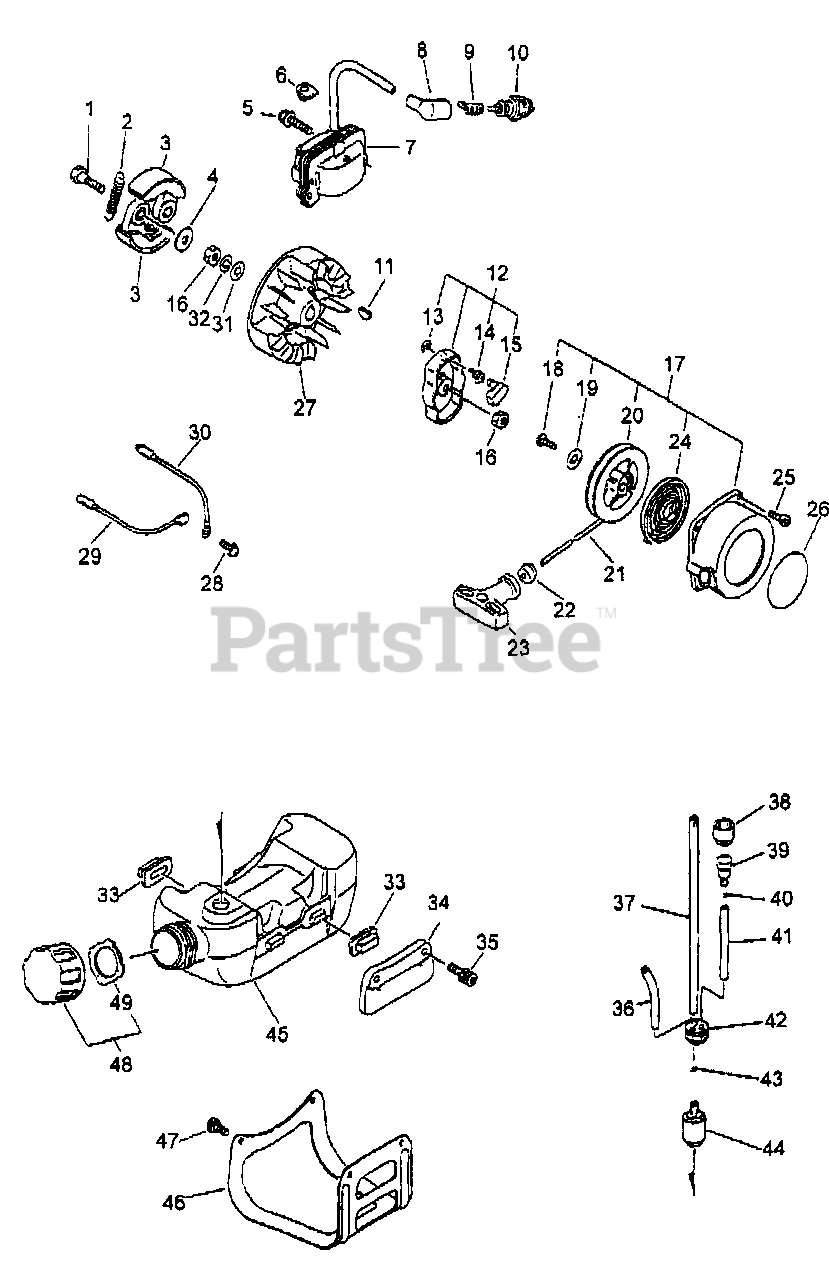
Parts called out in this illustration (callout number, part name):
1	BOLT, CLUTCH M6
2	SPRING, CLUTCH
3	SHOE, CLUTCH
4	WASHER 6.2×19×1.0
5	BOLT 5×20
7	COIL, IGNITION
8	CAP, SPARK PLUG
9	TERMINAL, SPARK PLUG
10	SPARK PLUG - BPM7A
11	KEY, WOODRUFF
12	PAWL ASSY, STARTER
13	E-RING 4
14	SPRING, RETURN
15	PAWL, STARTER
16	NUT 8×1.25
17	STARTER ASSY
20	REEL, ROPE
21	ROPE, STARTER 4.0×880
22	GUIDE, ROPE
23	GRIP, STARTER
24	SPRING, RECOIL
25	BOLT 4×14
26	LABEL, ECHO
27	FLYWHEEL
28	SCREW 5×10
29	LEAD 170 MM
30	LEAD - GROUND
31	WASHER 8.5×16×1.2
32	WASHER, SPRING 8
33	CUSHION, FUEL TANK
34	BRACKET, FUEL TANK
35	BOLT 5×20
36	PIPE, FUEL RETURN 3×6×90 MM CLEAR
37	PIPE, FUEL 3x-5x-180
38	HOLDER, VENT
39	VENT ASSY
41	PIPE, FUEL VENT 3×5×50
42	GROMMET, FUEL
43	CLIP 6 MM
44	FILTER, FUEL
45	TANK, FUEL
46	GUARD, FUEL TANK
47	BOLT 5×12
48	CAP ASSY
49	GASKET, FUEL CAP
